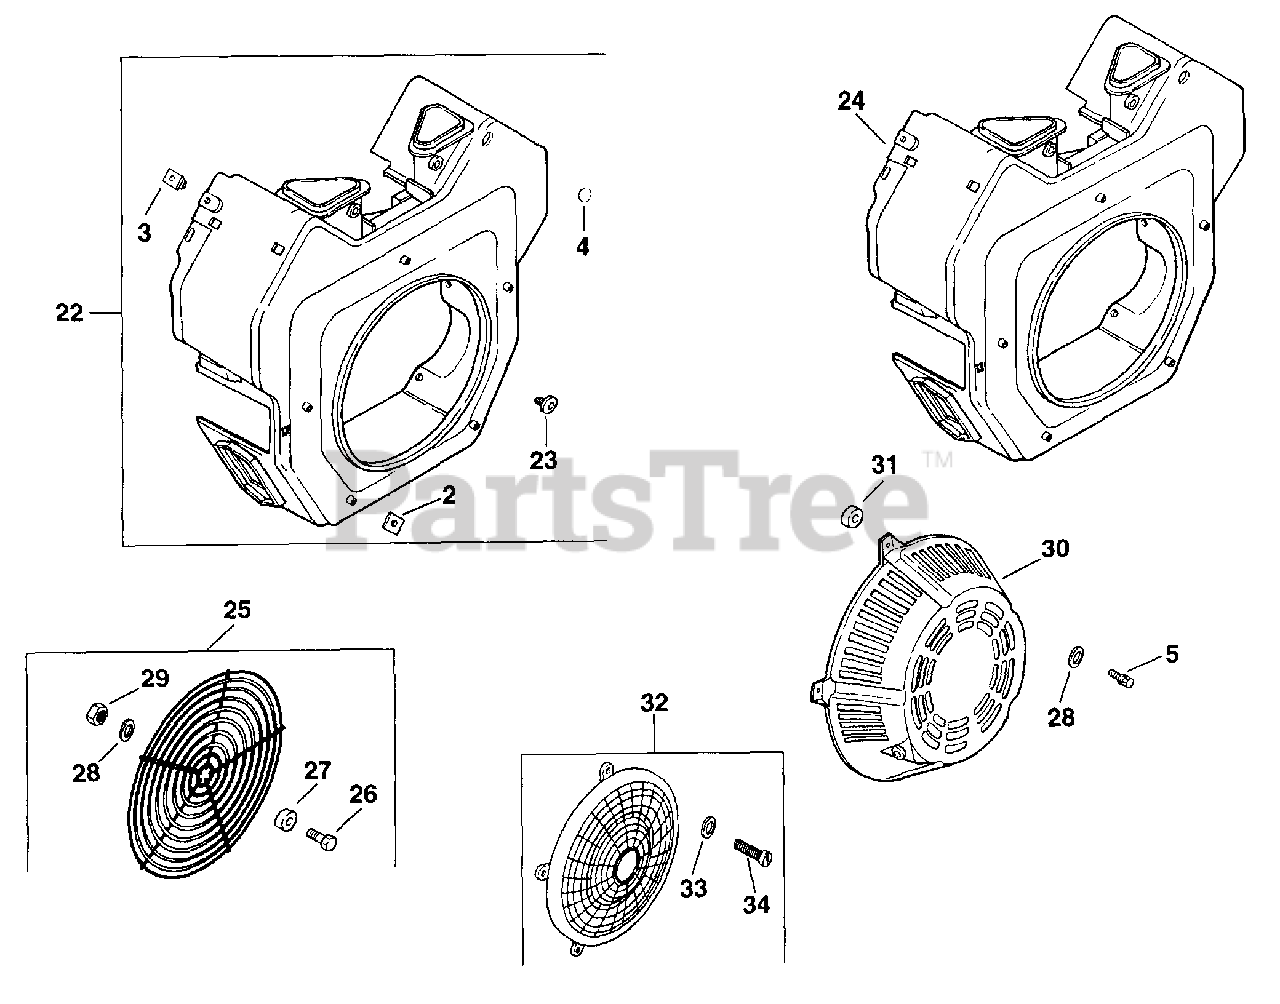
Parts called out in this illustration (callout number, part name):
2	NUT, PLASTIC (KM)-USE 25 100 37-S
3	NUT, PLASTIC
4	PLUG, BUTTON 9/16
5	SCREW - USE M-545016
22	HOUSING - USE 24 027 86
23	SCREW, SKT SET #10-24X1/4"
32	KIT, FIXED GUARD
33	WASHER, FLAT 7/32"
34	SCREW, LBD SCKT PAN M5X0.8X10
